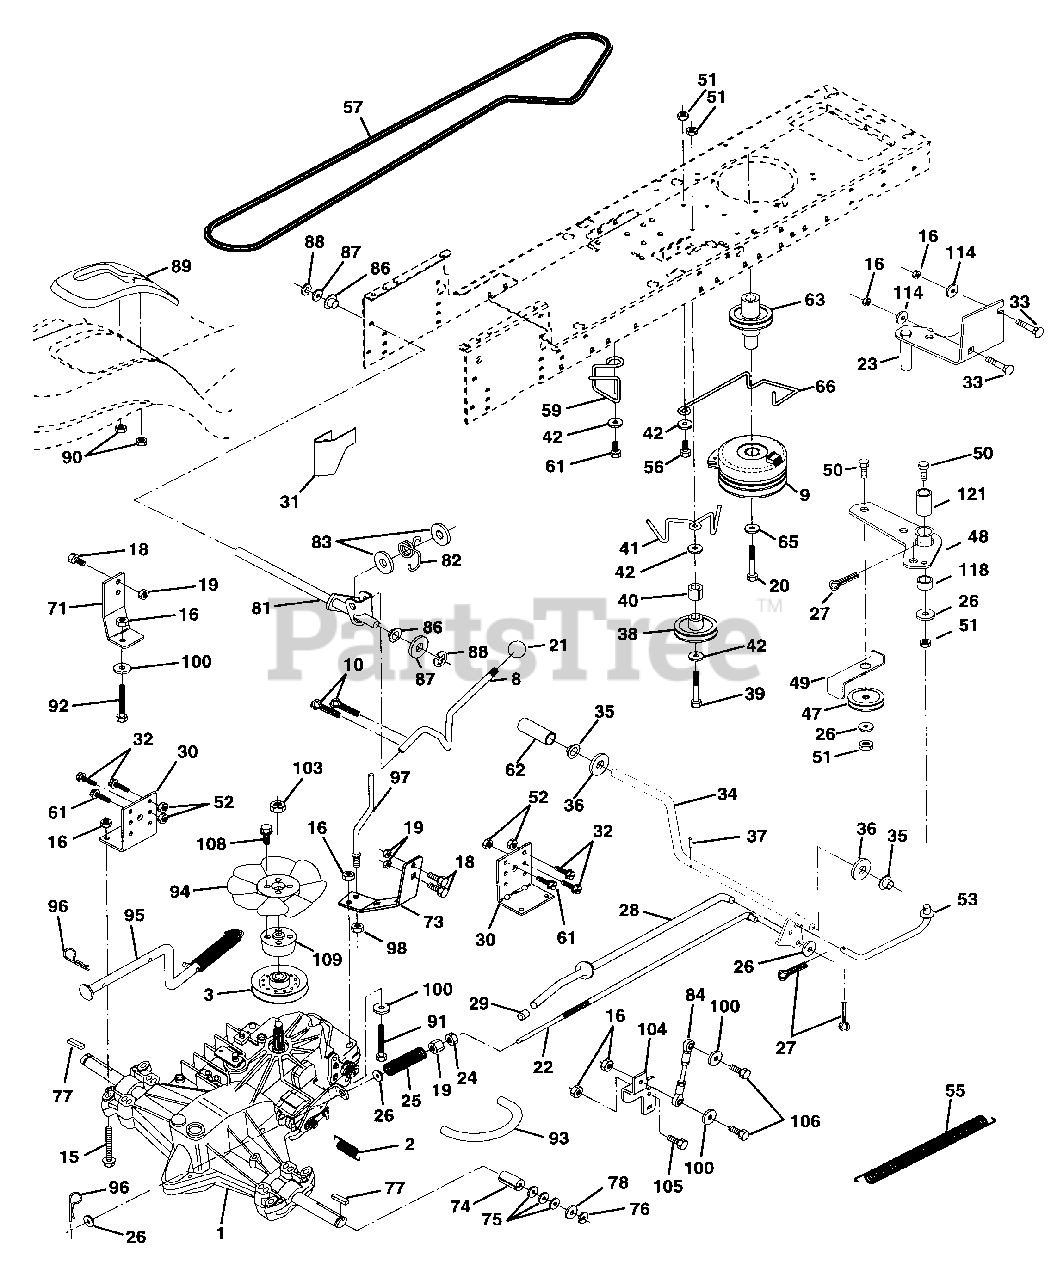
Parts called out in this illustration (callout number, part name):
1	Transaxle Assembly
2	Spring, Return, Brake
3	Pulley, Transaxle
8	Rod Shift Fender STLT
9	Clutch, Elect. EVX LT Mag 5217-2
10	Pin Cotter 1/8 x 1 CAD
15	Bolt Hex FLGHD 5/16-18 Gr. 5
16	Nut Lock Hex W/Ins. 5/16-18 Unc P
18	Bolt Fin Hex 3/8-16 Unc x 1 Gr. 5
19	Nut Lock Hex W/Wsh 3/8-16 Unc
20	Bolt Hex 7/16-20 x 4-1/4 Ga. 5
21	Knob, Duckhead 1/2-13
22	Rod, Brake Hydro
23	Bracket, Asm Clutch Mtg EVX
24	Nut
25	Spring, Brake Rod
26	Washer
27	Pin Cotter 1/8 x 3/4 CAD.
28	Rod, Parking Brake
29	Cap, Parking Brake
30	Bracket, Transaxle
31	Keeper Belt Lh
32	Bolt Hex Hd 5/16-18 Unc x 3/4
33	Bolt Rdhd Sqnk 5/16-18 UNC x 3/4
34	Shaft, Foot Pedal
35	Bearing, Nylon
36	Washer
37	Pin, Roll
38	Pulley, Idler, Flat
40	Spacer, Split
41	Keeper, Belt Idler
42	Washer 13/32 x 13/16 x 12 Gauge
47	Pulley, Idler, V-Groove
48	Bellcrank Assembly
49	Retainer, Belt
50	Bolt
52	Nut Crownlock 5/16-18
53	Link, Clutch
55	Spring, Return, Clutch
56	Bolt Fin Hex 3/8-16 UNC x 1-1/4
57	V-Belt, Ground Drive
59	Keeper, Center Span
61	Screw Thdrol. 3/8-16 x 3/4 Ty. TT
62	Cover, Pedal
63	Pulley, Clutch Electric EVX
65	Washer
66	Keeper Belt Engine
71	Strap Torque Lh Hydro
73	Strap Torque Rh Hydro
74	Spacer, Split
75	Washer 25/32 x 1-1/4 x 16 Gauge
77	Key, Square
78	Washer 25/32 x 1-5/8 x 16 Gauge
81	Shaft Asm. Cross Hydro
82	Spring Torsion I/A
83	Washer 17/32 x 3/4 x 16 Ga.
84	Rod, Tie Hydro
86	Bushing Rod Steering 629/632 ID
87	Washer 21/32 x 1-1/4 x 16 Ga.
88	Ring Klip #5304-62
89	Console, Shift
90	Nut Self-Thd Wsh-Hd 1/4 Zinc
91	Bolt Fin Hex 5/16-18 x 2-1/4
92	Bolt Fin Hex 5/6-18 Unc x 1-1/2
93	Line Fuel Hydro 4"
94	Fan, Hydro 7"
95	Control Asm Bypass Hydro
96	Retainer Spring 1" Zinc/Cad
97	Keeper Belt Rh Hydro
98	Nut Keps Hex 3/8-16 Unc
100	Washer 11/32 x 3/4 x 16 Ga.
103	Nut Nylon Insert 1/2-20 Unf.
104	Arm, Control Hydro
105	Screw Cap Hex 5/16 x 18 x 1
106	Bolt Fin Hex 5/16-18 Unc x 1-1/4
108	Screw Hex Wh Hd #10-24 x
109	Adaptor Fan Hydro LT Hyd Alum
114	Washer 11/32 x 3/4 x 14 Ga.
118	Spacer Bellcrank
121	Nyliner Clutching STL
